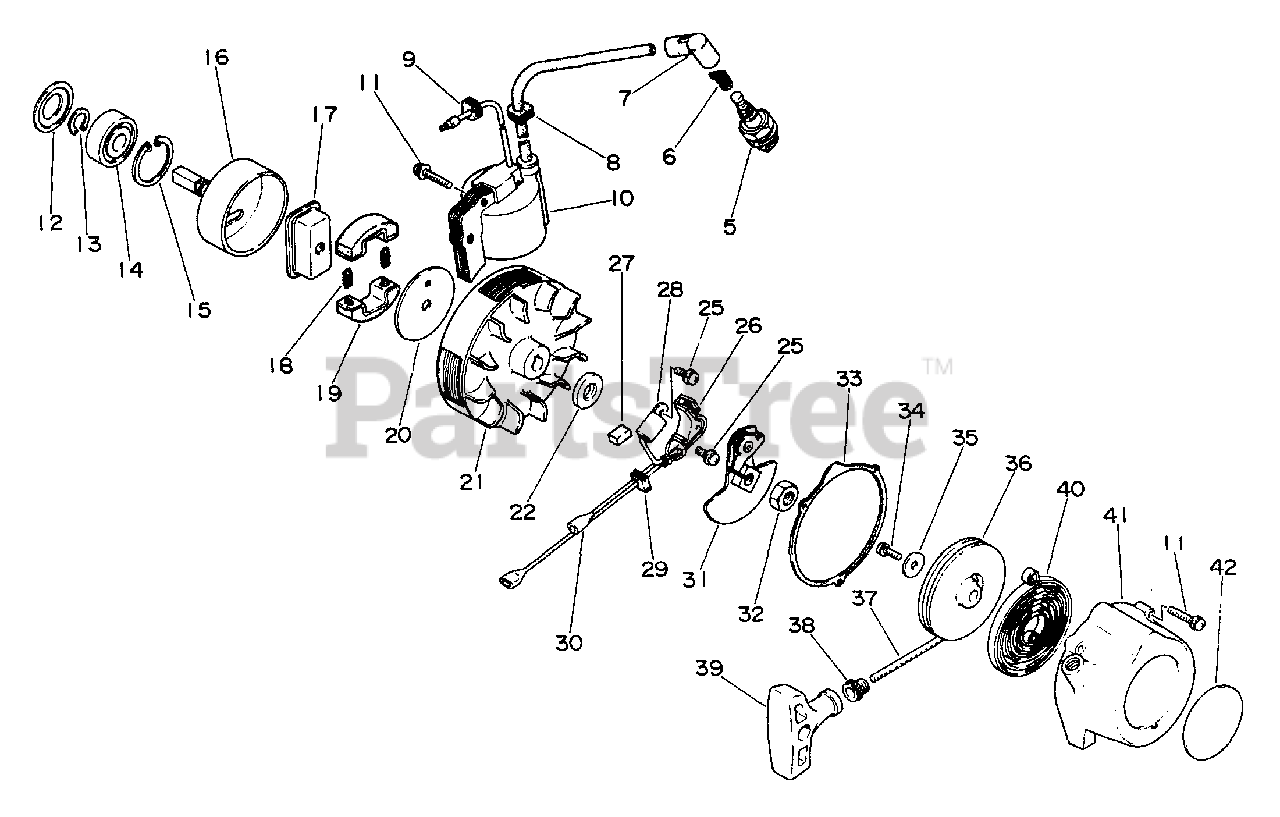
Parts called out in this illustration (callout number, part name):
5	SPARK PLUG - CJ8
6	TERMINAL, SPARK PLUG
7	CAP, SPARK PLUG
10	COIL, IGNITION
11	SCREW 4×20
12	STOPPER, PIPE
13	RING, RETAINING - 12
14	BEARING, BALL
15	RING, SNAP Ø32
16	DRUM, CLUTCH
17	BOSS, CLUTCH
18	SPRING, CLUTCH
19	SHOE, CLUTCH
20	PLATE, CLUTCH
21	FLYWHEEL
25	SCREW 4×10
26	CONTACT POINT SET
27	PAD, OIL
28	CONDENSER
29	GROMMET, LEAD
30	LEAD - GROUND
31	PAWL ASSY, STARTER
32	NUT 8×1.25
33	GASKET, STARTER
34	SCREW - 4×10
35	WASHER 4.1×15.5×1T
36	REEL, ROPE
37	ROPE, STARTER 3.0×850
38	GUIDE, ROPE
39	GRIP, STARTER
40	SPRING, RECOIL
41	CASE, STARTER
42	LABEL - ECHO
